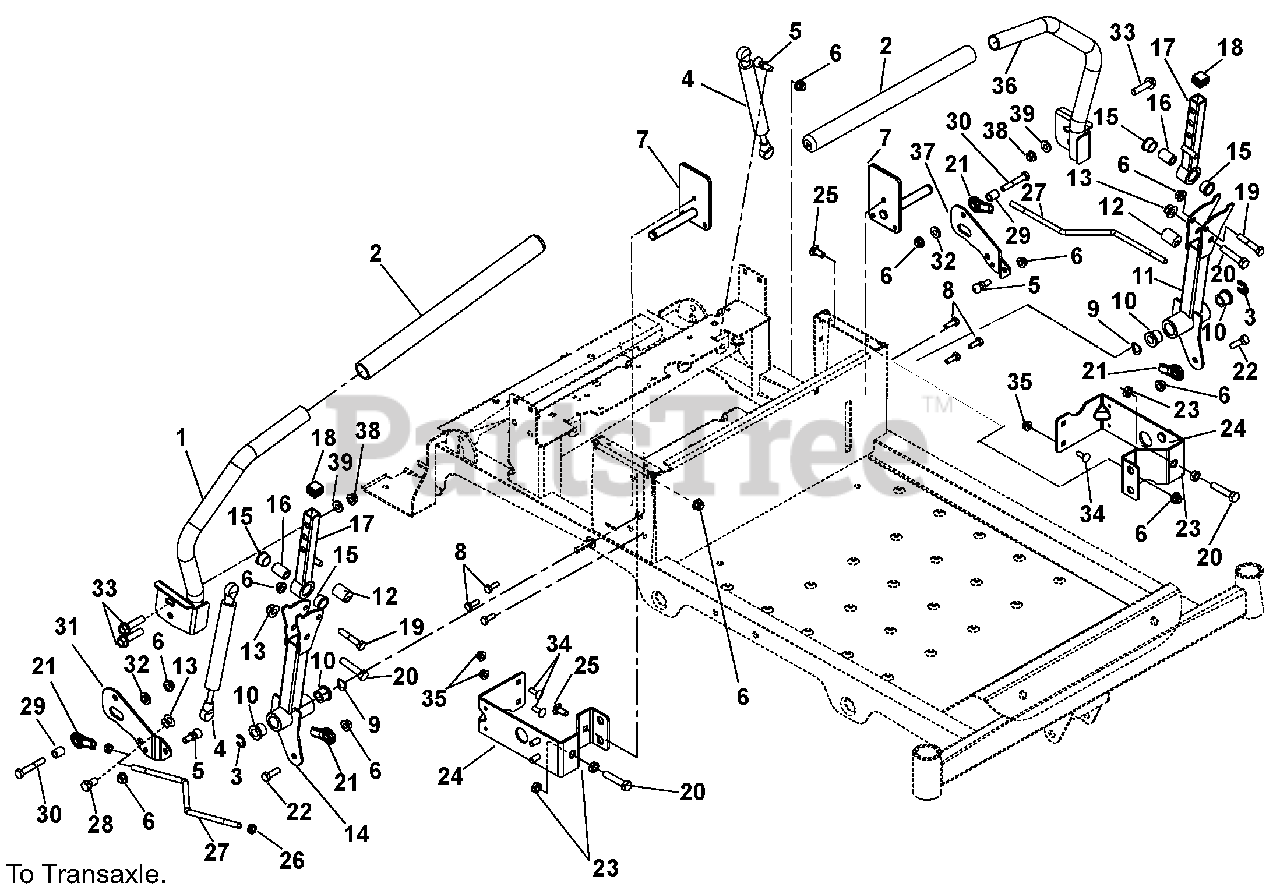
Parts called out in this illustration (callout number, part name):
1	Weldment, Steering Handle Right Hand
2	Grip, Handlebar 15" Foam
3	Ring, Retaining External .438 x 1.00 x 0.83
5	Stud, Ball
6	Nut, .31-18 Flange
7	Weldment, Steering Shaft
8	Screw, Tapping .25-20 x .50 Hex Washer Head
9	Washer, Wave
10	Bushing, Flanged
11	Weldment, Lower Control Arm
12	Bushing, Eccentric
13	Nut, .38-16 Nyloc Flange
14	Weldment, Lower Control Right Hand
15	Bushing, Flanged
16	Spacer, .375 x .625 x .970
17	Weldment, Upper Control Arm
18	Cap Plug, Square
19	Bolt, Hex .31-18 x 1.75
20	Bolt, Hex .375-16 x 1.75
21	Alignaball, 5/16 RH Thread
22	Bolt, Hex .31-18 x 1.00
23	Nut, Hex Jam .375-16
24	Bracket, Speed Adjustment/Seat Pivot
25	Bolt, Round Head Square Neck .31-18 x .75
26	Nut, Jam, .31-24
27	Wireform, Steering Link
28	Bolt, Hex .38-16 x .75
29	Spacer, .328 x .500 x .625
30	Bolt, Hex .31-18 x 2.00
31	Plate, Dampener Right Hand
32	Bushing, Flanged
33	Bolt, Serrated Hex Flange Washer Head .375-16 x 1.25
34	Bolt, Round Head Square Neck .25-20 x .75
35	Nut, Locking Nylon Flange .25-20
36	Weldment, Steering Handle Left Hand
37	Plate, Damper Left Hand
38	Nut, Locking Center Jam .375-16
39	Washer, Flat Steel .406 x .812 x .065
